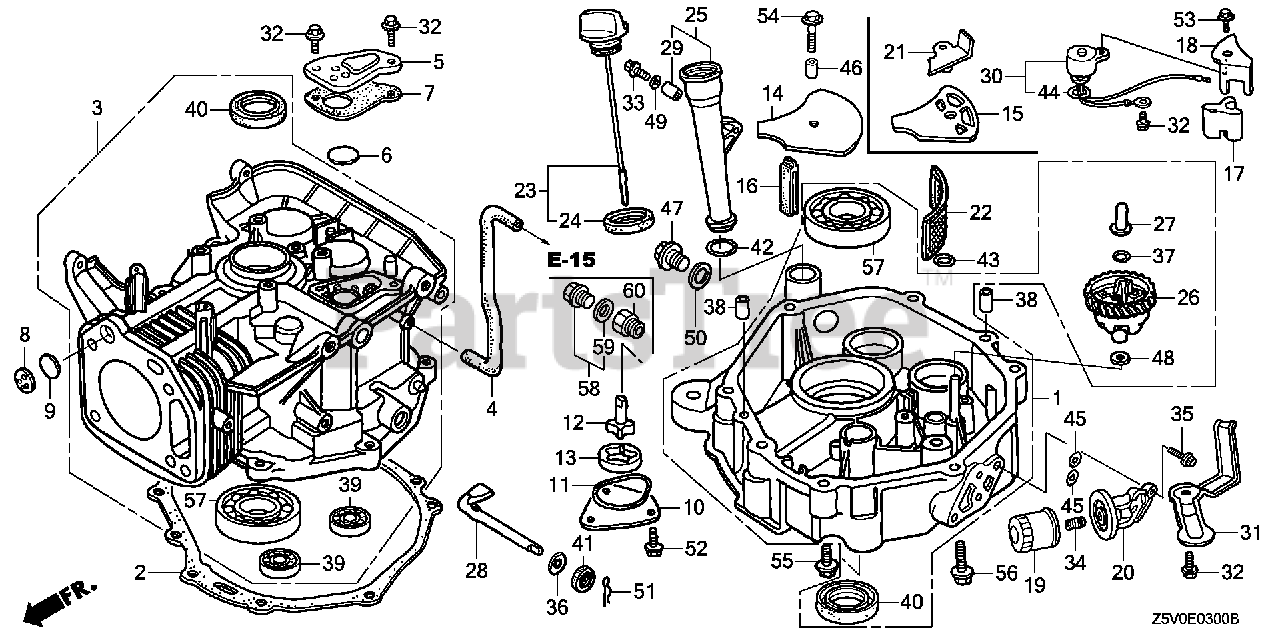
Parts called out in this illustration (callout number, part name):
1	PAN ASSY., OIL
2	GASKET, OIL PAN
3	CYLINDER ASSY.
4	TUBE, BREATHER
5	CAP, BREATHER CHAMBER
6	VALVE, BREATHER
7	GASKET, BREATHER CAP
8	PLATE, ONE-WAY VALVE
9	VALVE, ONE-WAY
10	COVER, OIL PUMP
11	O-RING, PUMP COVER
12	ROTOR (INNER)
13	ROTOR, OIL PUMP (OUTER)
15	PLATE, OIL FILTER
16	RUBBER, OIL RETURN
17	STOPPER, OIL
18	PLATE, OIL STOPPER
19	FILTER, OIL (FILTECH TOYO ROKI) (SOLD INDIVIDUALLY)
19	FILTER, OIL
19	FILTER, OIL (Honda Code 6836290). (SOLD INDIVIDUALLY)
20	BASE, OIL FILTER
21	PLATE, SUCTION
22	SCREEN, OIL FILTER
23	CAP ASSY., OIL FILLER
24	GASKET, OIL FILLER CAP
25	EXTENSION, OIL FILLER
26	GOVERNOR ASSY.
27	SLIDER, GOVERNOR
28	SHAFT, GOVERNOR ARM
29	COLLAR, EXTENSION Use up to Engine SN 1257294.
30	SWITCH, OIL LEVEL
31	PROTECTOR, SWITCH
32	BOLT, FLANGE (6X12) (CT200)
33	BOLT, FLANGE (6X35)
34	HOLDER, OIL FILTER
35	BOLT, FLANGE (6X25) Use up to Engine SN 2056819.
36	WASHER, THRUST (8.1MM)
37	CLIP, GOVERNOR HOLDER
38	PIN, DOWEL (8X12)
39	BEARING, RADIAL BALL (6202)
40	OIL SEAL (35X52X8) (NOK)
41	OIL SEAL (8X14X5)
42	O-RING (22.5X2.2) Use from Engine SN 1257295.
43	O-RING (11.8X2.4)
44	O-RING (11.8X2.4)
45	O-RING (11X1.9) (NOK)
47	BOLT, DRAIN PLUG (20MM)
48	WASHER, PLAIN (6MM)
49	WASHER, PLAIN (6MM)
50	WASHER, DRAIN PLUG (20MM)
51	PIN, LOCK (10MM)
52	BOLT, FLANGE (6X12) Use up to Engine SN 1543277.
53	BOLT, FLANGE (6X16) Use from Engine SN 2056820.
54	BOLT, FLANGE (6X25)
55	BOLT, FLANGE (8X40)
56	BOLT, FLANGE (8X60)
57	BEARING, RADIAL BALL (6207)
